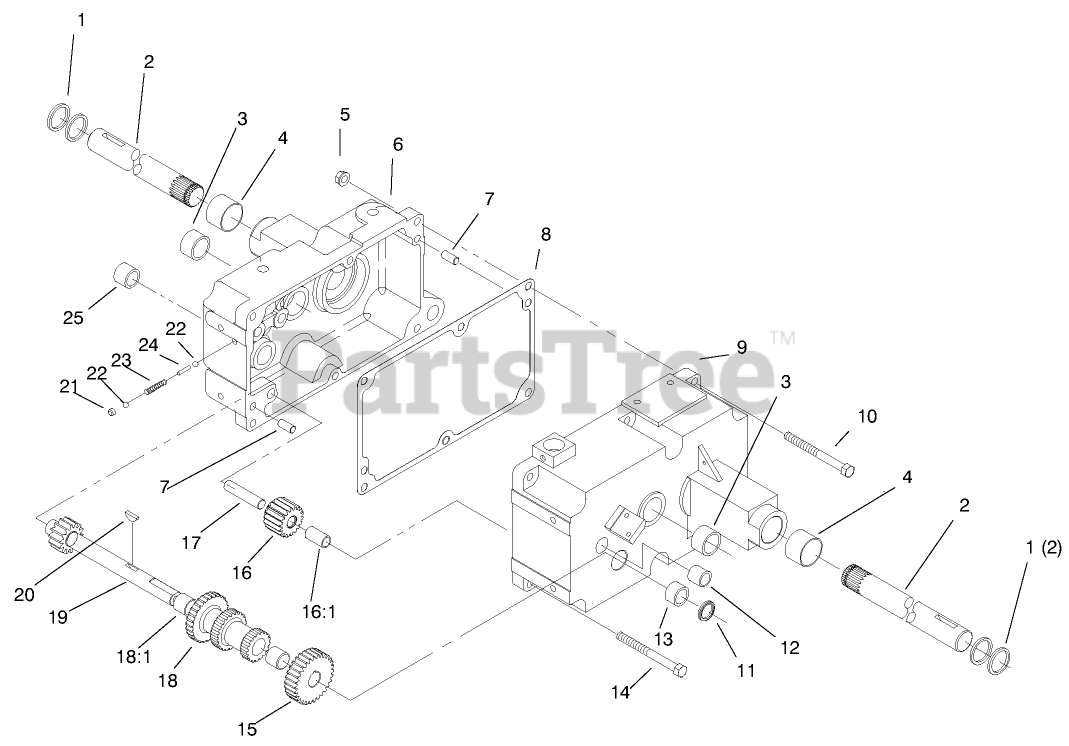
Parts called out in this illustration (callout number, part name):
1	SEAL-OIL
2	AXLE-REAR
2	BEARING-BALL
3	BEARING-NEEDLE
3	WASHER
4	BEARING
4	END CAP-DIFFERENTIAL
5	NUT-LOCK, NI
5	GEAR-AXLE DIFFERENTIAL
6	CASE-RH TRANS
6	RING-SNAP
7	PIN-DOWEL
7	WASHER-THRUST
8	GASKET-TRANSMISSION
8	GEAR-DIFFERENTIAL RING, 43T
9	CASE-TRANS LH
9	GEAR ASM
10	SCREW-HH
10	GEAR-PINION, 11T
11	SEAL-OIL
11	NUT-HEX
12	PLUG-PIPE, SQH
13	BEARING-NEEDLE
14	SCREW-HH
14	RAIL-SHIFT
15	GEAR-CLUSTER SHAFT
15	RAIL-REAR SHIFT
16	GEAR/BUSHING ASM-REVERSE IDLER
16	PIN-ROLL
17	PIN-DIFFERENTIAL
17	FORK-SHIFT
18	GEAR-CLUSTER
18	BOLT-DETENT
19	SHAFT-CLUSTER
20	SPRING-SHIFT STOP
21	CUP-PLUG
21	BALL-DETENT
22	BALL-DETENT
22	BEARING-NEEDLE
23	SPRING-SHIFT STOP
24	PIN-SHIFT
24	GEAR-SHAFT REDUCTION
25	BEARING-NEEDLE
25	SHIFT ASM
26	GEAR
26:1	BEARING-NEEDLE
27	GEAR-LOW AND REVERSE
28	GEAR-HI AND 2ND
29	GEAR
29:1	BEARING-NEEDLE
30	GEAR-SLIDING
31	SHAFT-INPUT
32	WASHER-THRUST
33	BEARING-NEEDLE
34	SEAL-OIL
